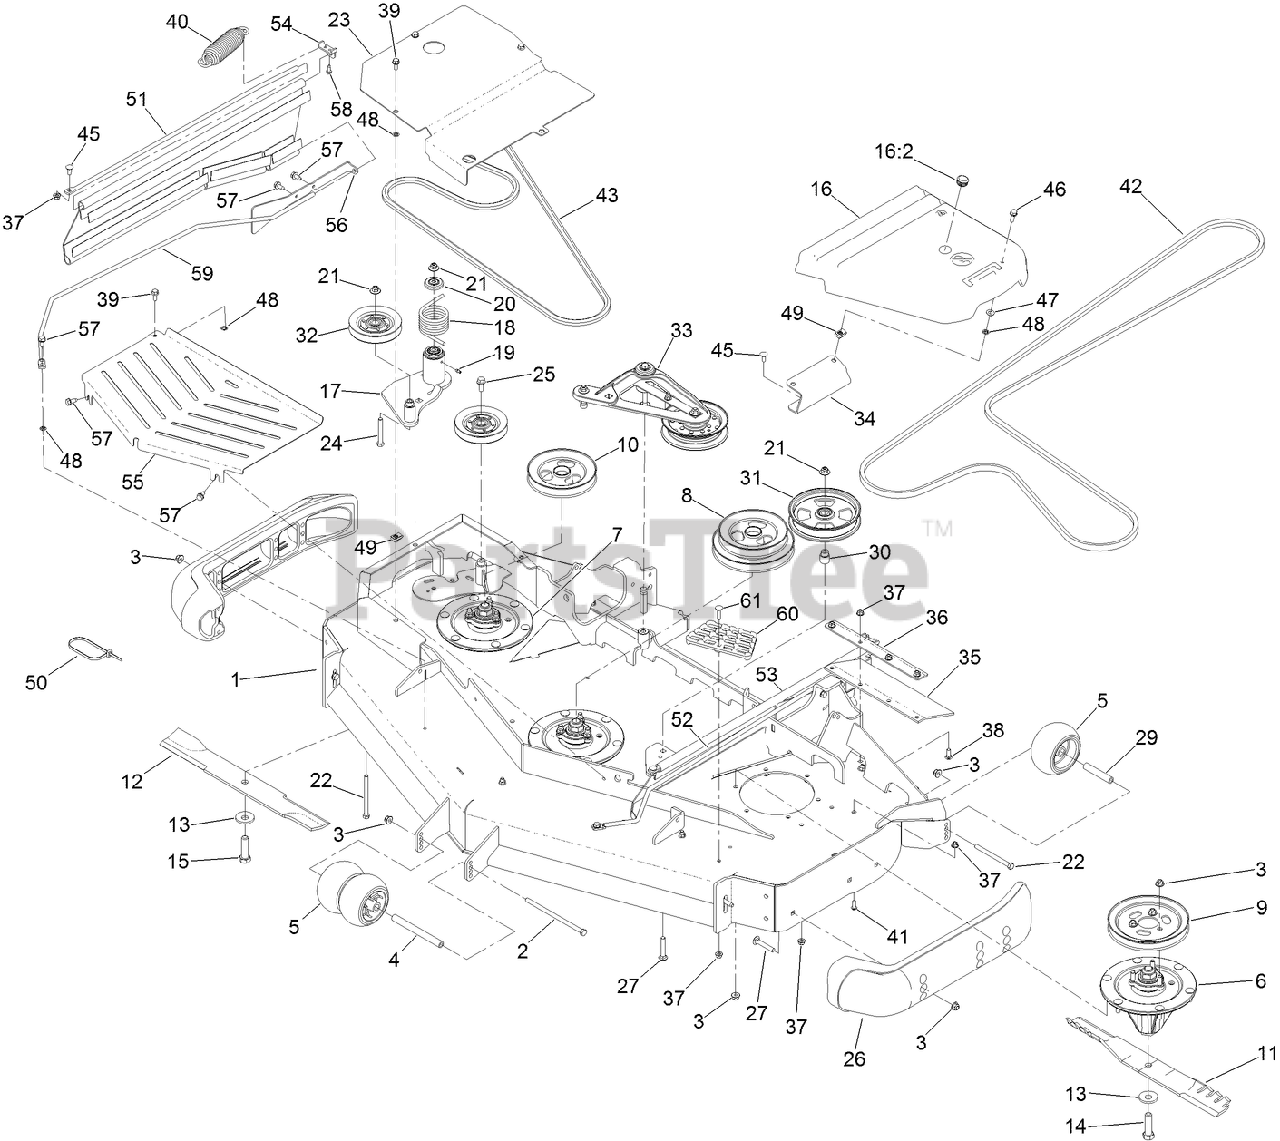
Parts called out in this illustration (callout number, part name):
1	DECK DECAL ASM
2	SCREW-HH
3	NUT-HF, NI
4	SPACER-WHEEL
5	ROLLER-SCALP, ANTI
6	SPINDLE ASM
7	LH SPINDLE ASM
8	PULLEY
9	PULLEY
10	PULLEY
11	BLADE-ATOMIC, 20.5IN
12	BLADE-ROTARY, 20.5IN LOW FLOW
13	WASHER-BLADE BOLT, HEAVY
14	SCREW-BLADE
15	SCREW-BLADE, LH
16	LH BELT COVER ASM
16:2	PLUG-PLASTIC
17	DECK IDLER ASM
18	SPRING-TORSION
19	FITTING-GREASE
20	GUARD-TOP
21	NUT-FLANGE, NI
22	SCREW-HH
23	COVER-SPINDLE
24	SCREW-HH
25	SCREW-HHF
26	SKID-BUMPER, DECK
27	SCREW-HH
29	TUBE-SPANNER
30	BUSHING-IDLER
31	PULLEY-IDLER, FLAT
32	SHEAVE
33	DECK IDLER ASM
34	BRACKET-COVER, BELT
35	GUARD-TIRE
36	SUPPORT-OUTER FLAP
37	NUT-HF, NI
38	SCREW-CARR
39	SCREW-HHF
40	SPRING-EXTENSION
41	SCREW-HSBH
45	SCREW-CARR
46	SCREW-HHF
47	WASHER-THRUST
48	NUT-PUSH
49	NUT-U
50	TIE-CABLE
51	ROD-SUPPORT, UPPER
52	ROD SUPPORT WLDMNT, LOWER-LH
53	GUARD SIDE
54	BRACKET-MOUNTING, UPPER
55	SHIELD-FRONT,
56	BRACKET-MOUNTING, REAR
57	SCREW-HWHTF
58	SCREW-HWH
59	ROD SUPPORT WLDMNT, LOWER-RH
60	STEP-DECK
61	SCREW-CARR
